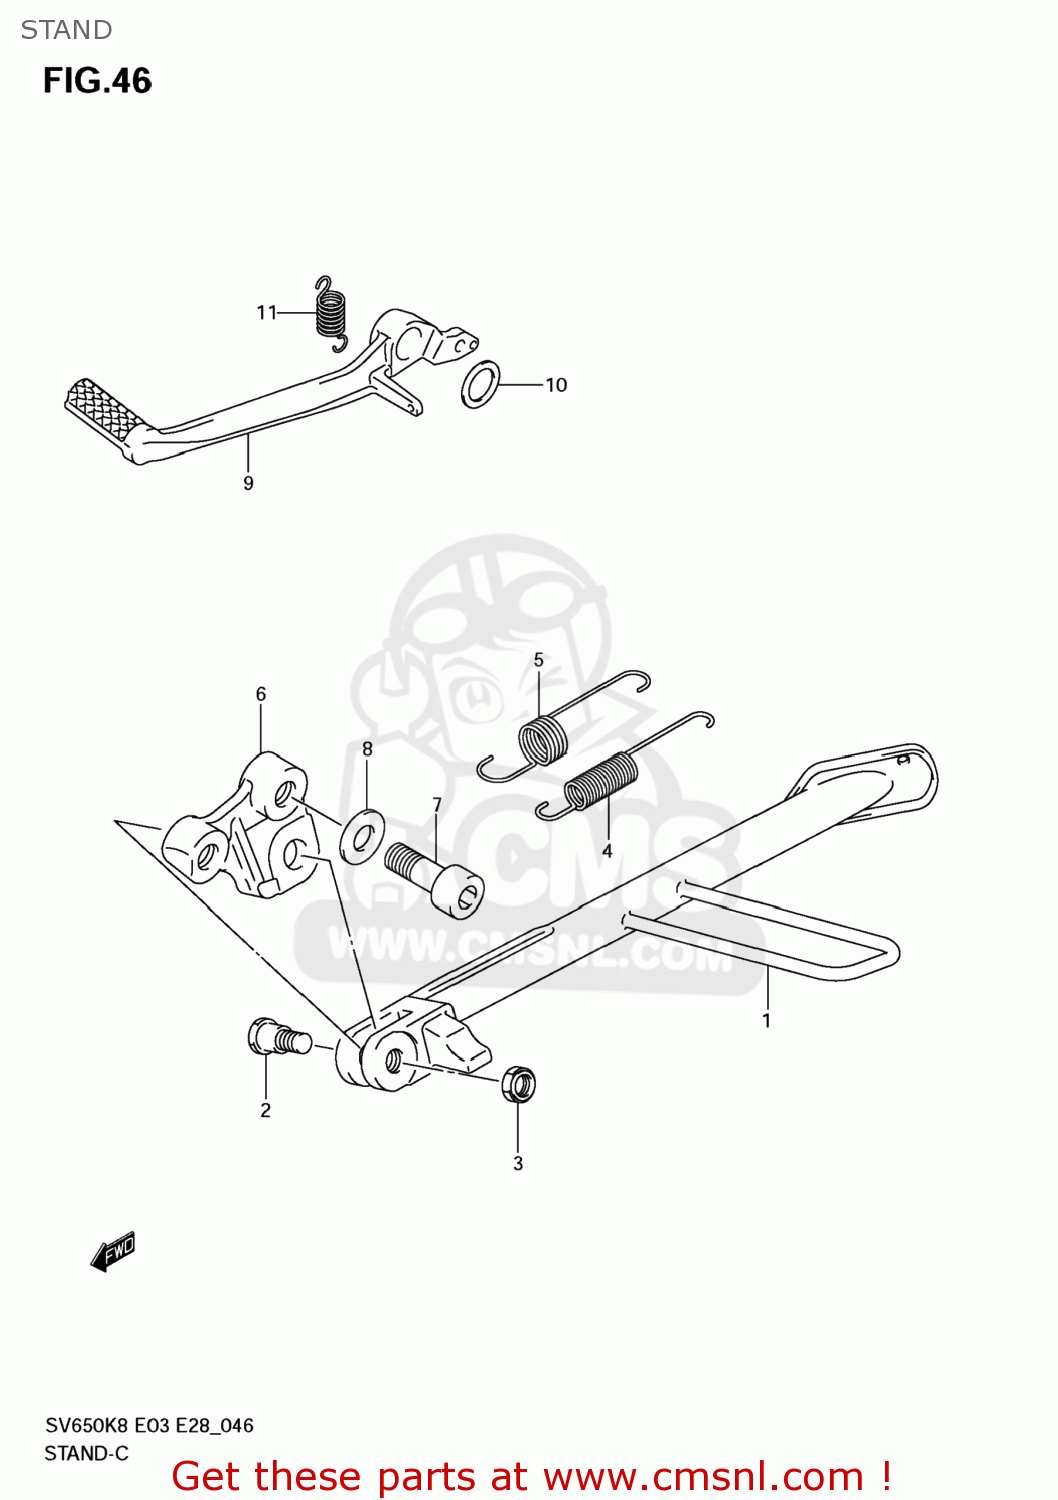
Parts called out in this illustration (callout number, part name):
1	STAND,PROP
2	BOLT(10X34)
3	NUT,PROP STAND
4	SPRING
5	SPRING
6	BRACKET,PROP STAND
7	BOLT(12X35)
8	WASHER(12.5X24X2.6)
9	PEDAL,BRAKE
10	WASHER(18X24X1)
11	SPRING
